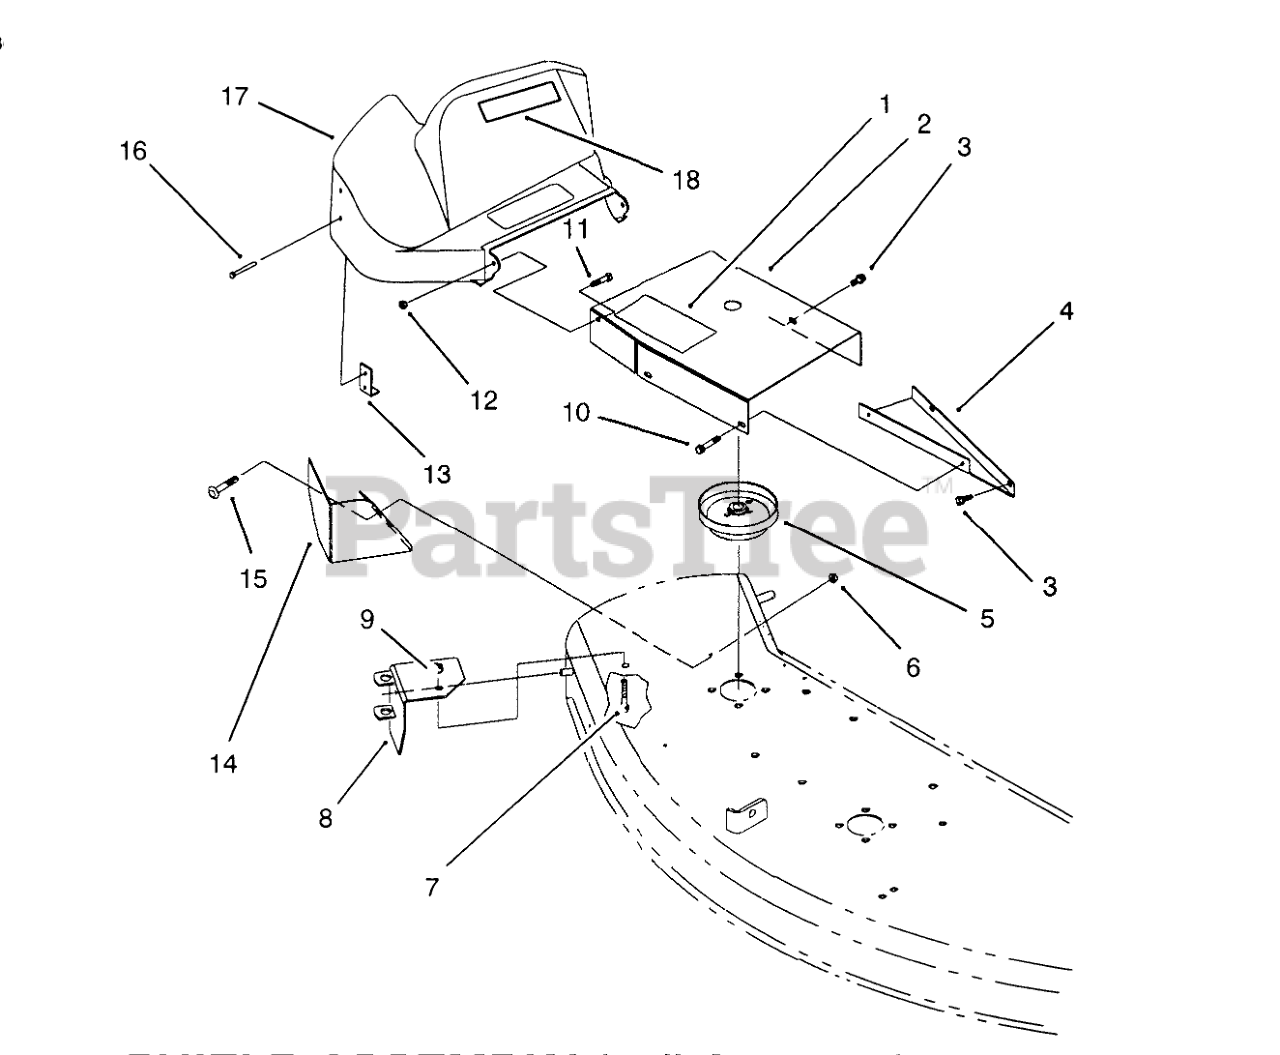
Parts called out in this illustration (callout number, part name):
1	DECAL-DANGER, THROWN OBJECT
2	Inner Shield Assembly (Incl. Ref. #1)
3	SCREW-HHF
4	48" ADAPTOR SHIELD B
5	PULLEY
6	NUT-LOCK, NI
7	SCREW-HH
8	PIVOT SUPPORT ASM
9	NUT-HF
10	Bolt
11	SCREW-HH
12	NUT-LOCK, NI
13	BRACKET-SUPPORT, SHIELD
14	48" DEFLECTOR B
15	SCREW-CARR
16	RIVET-POP
17	SHIELD-BELT
18	DECAL - DANGER
